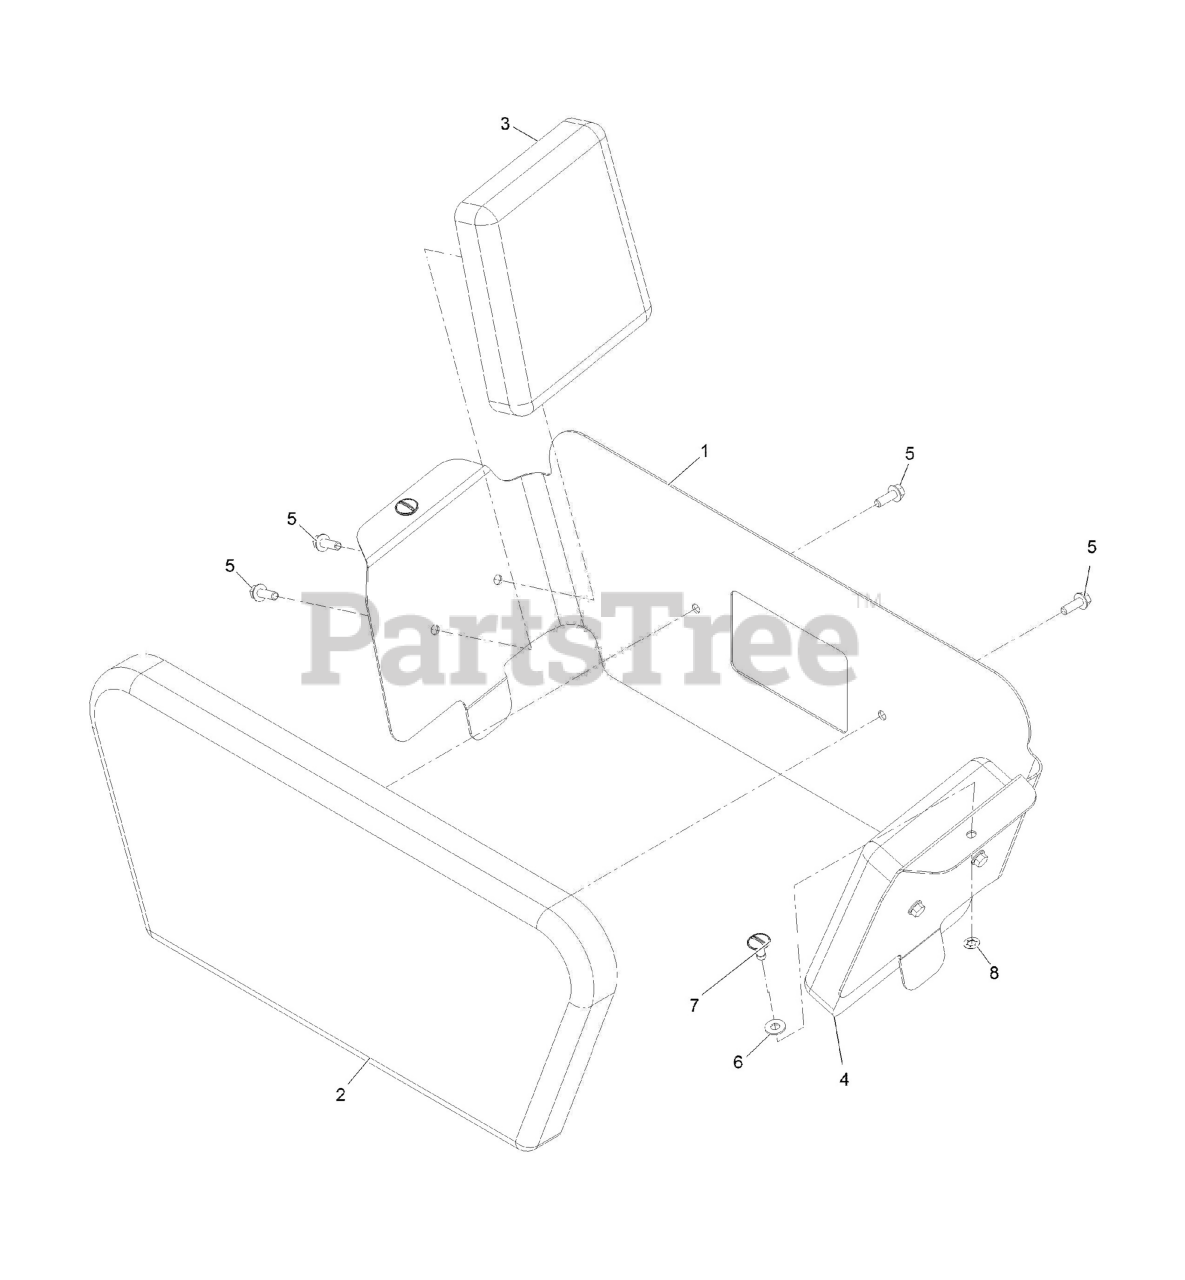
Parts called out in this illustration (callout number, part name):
1	BRACKET-PAD, KNEE
2	Pad-Knee, Center
3	PAD-KNEE, LH SIDE
4	PAD-KNEE, RH SIDE
5	SCREW-HHF
6	WASHER-FLAT
7	STUD-1/4 TURN
8	RETAINER-STUD
